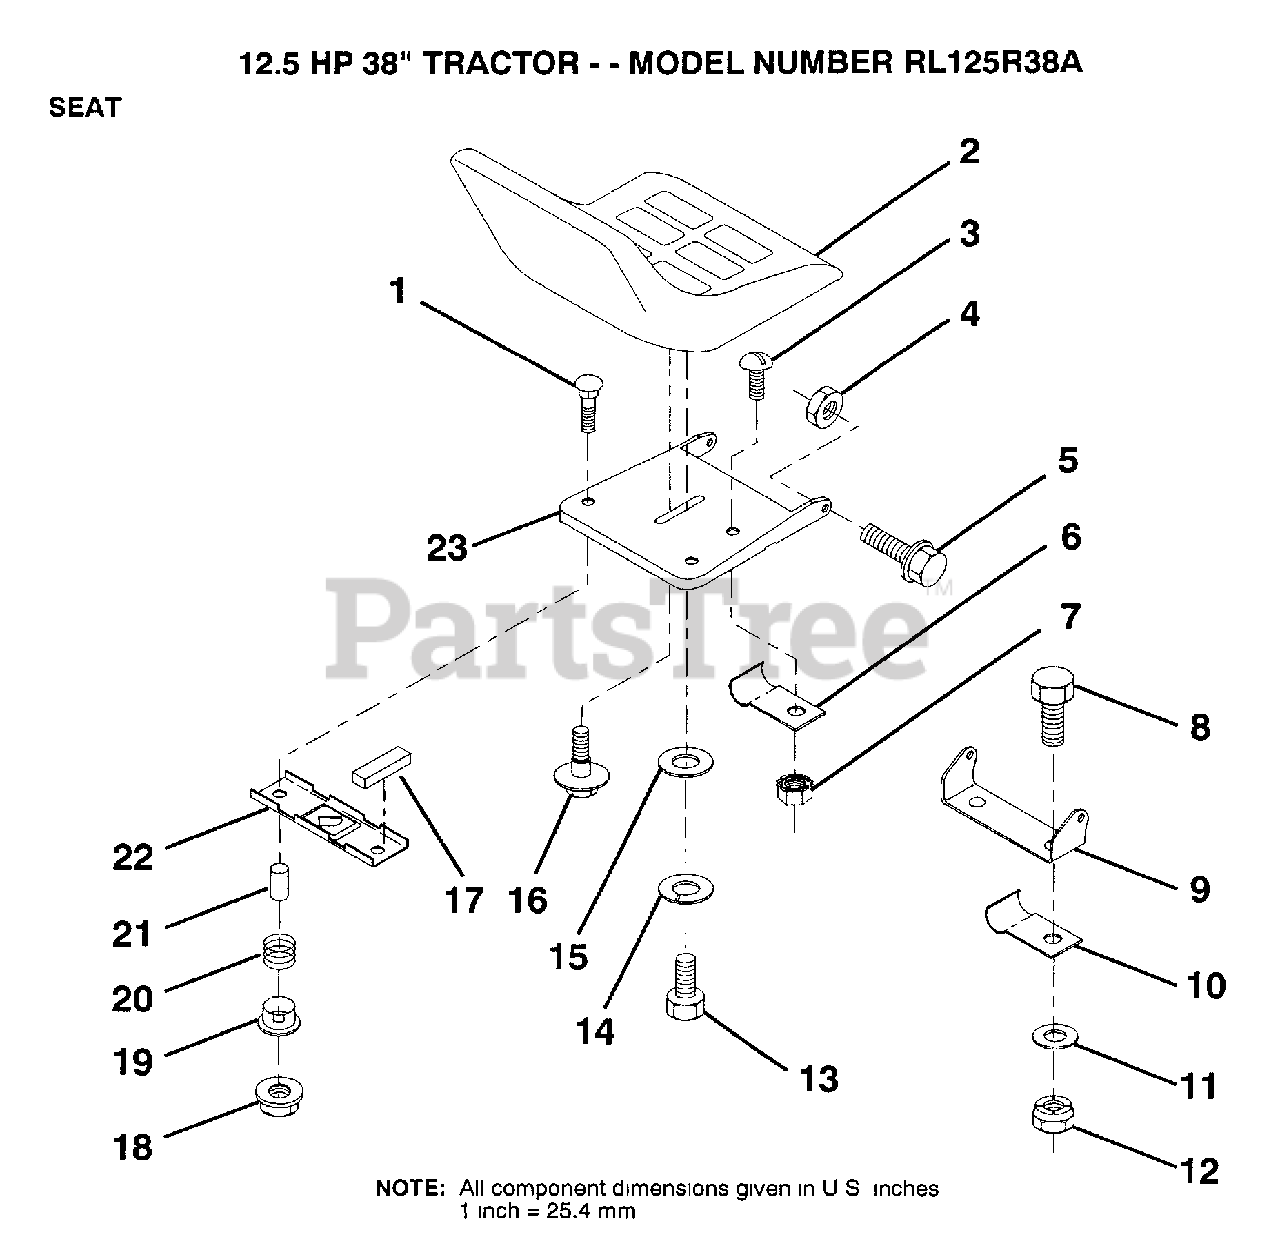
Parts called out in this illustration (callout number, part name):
7	"NUT,KEPS"
10	"CLIP,INSULATOR"
11	WASHER
13	BOLT
14	LOCKWASHER
15	WASHER
16	"BOLT,SHOULDER"
17	STRIP FORM
19	BUSHING
20	SPRING
21	SPACER SPLIT
22	BRKT SWITCH
